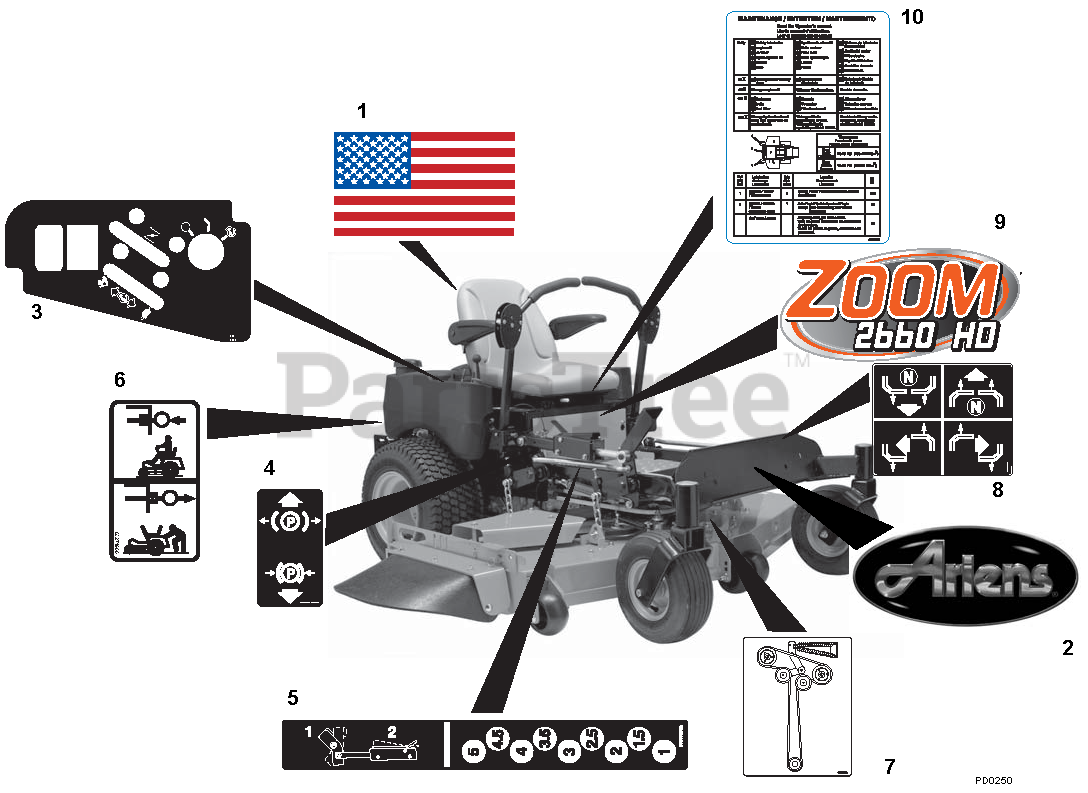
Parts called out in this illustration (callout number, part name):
1	DECAL, AMERICAN FLAG
2	DECAL, ARIENS JEWEL
3	DECAL, CONTROL PANEL COMPACT Z
4	DECAL, PARKING BRAKE LEVER
5	DECAL, HEIGHT OF CUT COMPACT-Z
6	DECAL, TRANSMISSION DISCONNECT
7	DECAL, BELT DIAGRAM
8	DECAL, INSTRUCTIONAL-STEERING
9	DECAL, ZOOM 2452 HD
10	DECAL-MAINTENANCE INSTRUCTIONS
